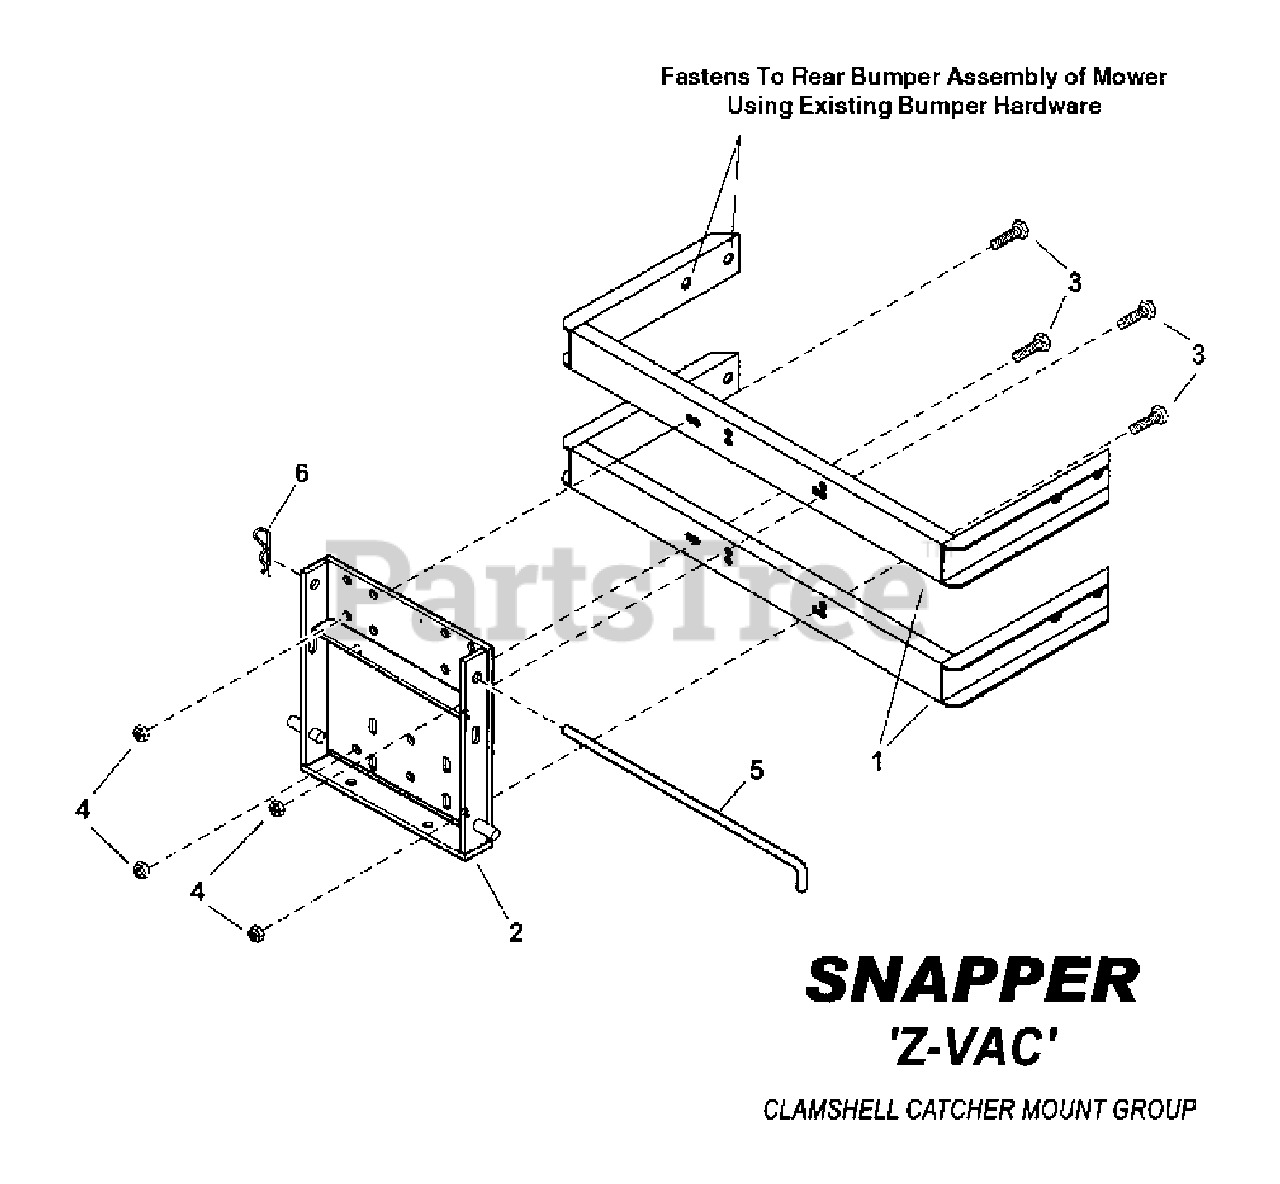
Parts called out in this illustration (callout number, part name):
1	STAND-OFF, Bumper Mount
2	WELDMENT, Bumper Mount Plate
3	SCREW, Hex Head Cap 5/16 X 3/4 GR5 YZ
4	NUT, Flange Lock 5/16-18 YZ
5	ROD, Hitch
6	PIN, Hair 1.6
